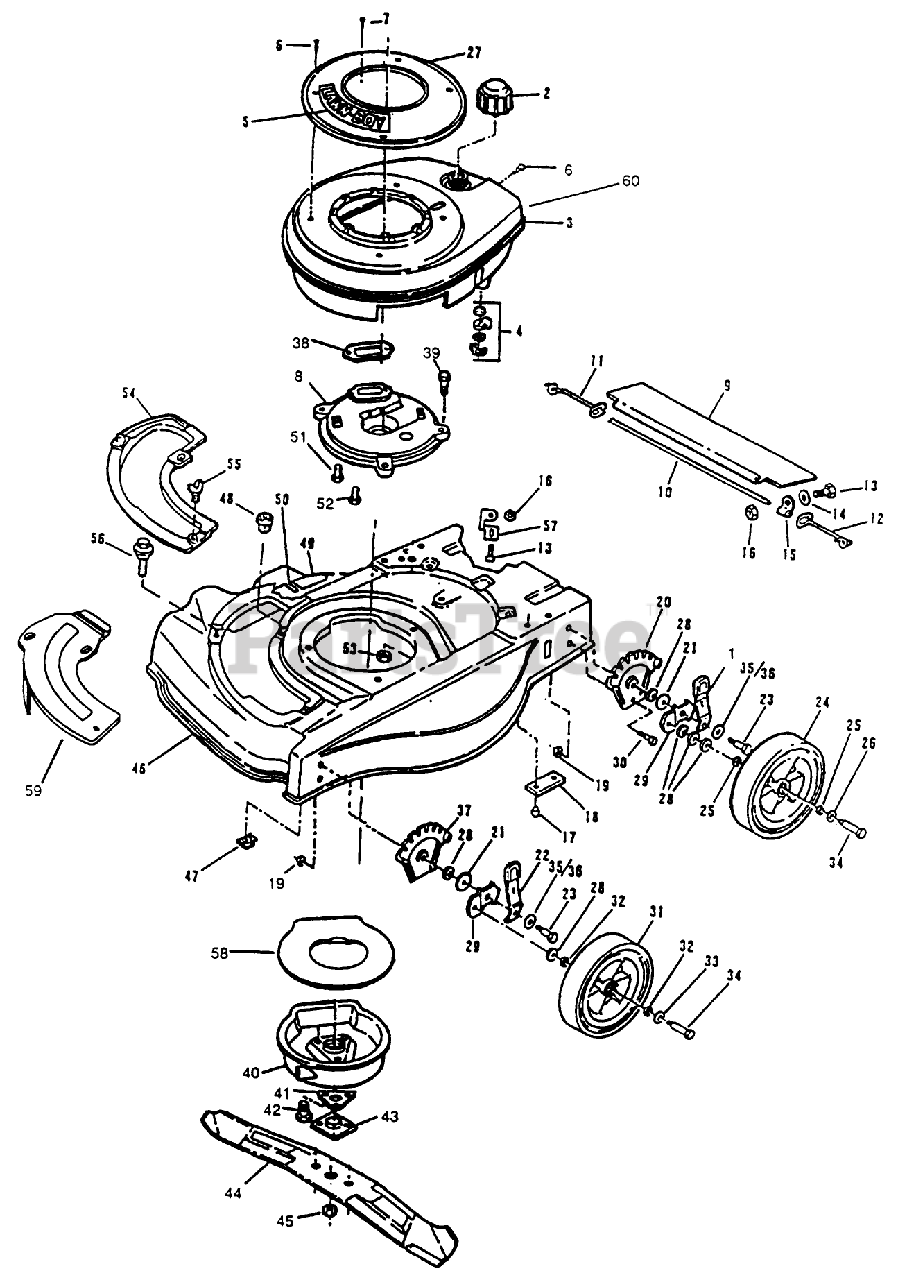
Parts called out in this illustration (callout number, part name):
1	KNOB&SPRING AY FORMCO
2	FUEL CAP & INSERT
3	SHROUD,TANK&VAL
4	SHUT OFF VALVE KIT
6	SCREW - SELF TAPPING
7	SCREW SEMS SM
10	ROD T/SHIELD ADV WIRE
11	SPRING;TRAILING SHIELD RH
12	SPRIG T/SHLD ASOC
14	WASHER F
15	CLAMP ROD KMC
16	LOCKNUT E
17	SCREW
19	LOCKNUT
21	WASHER
22	KNOB&SPRING FORMCO
23	BOLT
25	WASHER
26	SPACER
28	WASHER WROUGHT
31	WHEEL & TIRE KIT
32	WASHER
33	SPACER
34	BOLT WHEEL
35	WASHER
36	WASHER
37	PLATE HGT ADJ TRO
39	SCREW-HH
41	SUPPORT F
42	SCREW
43	PLATE AND COLLAR ASM
45	NUT-BLADE
47	NUT-CAGE
52	SCREW V
53	NUT-LOCK F
55	WING SCREW LAWRE
58	BAFFLE,MUFFLER S
